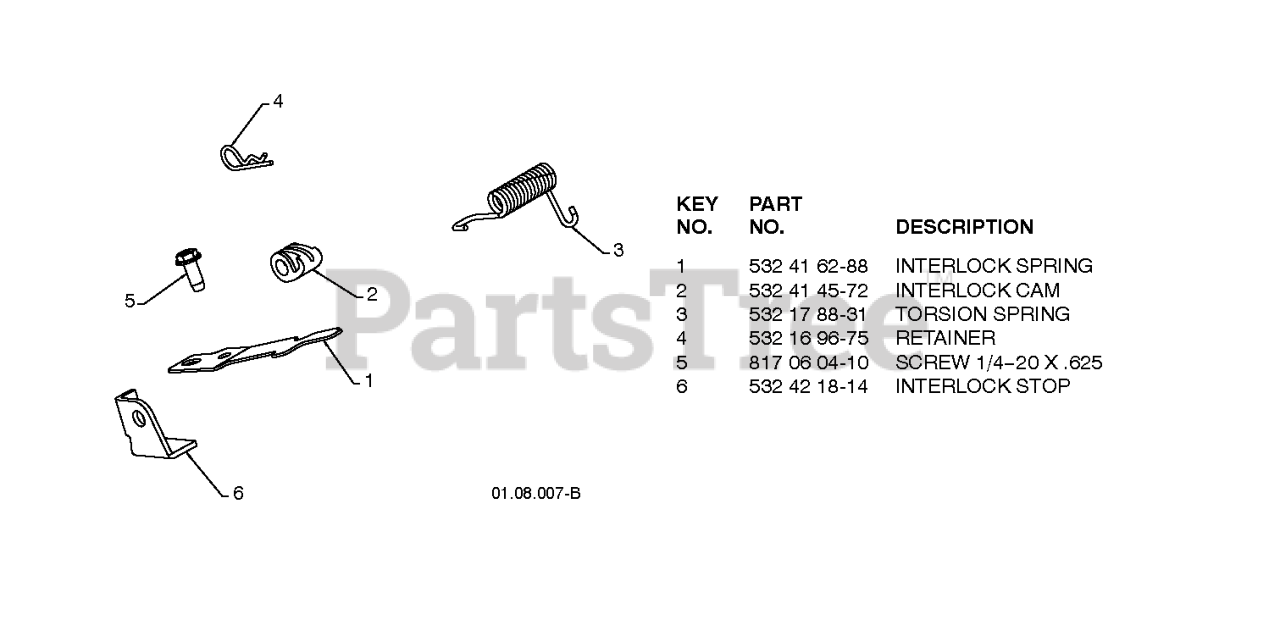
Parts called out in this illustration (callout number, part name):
1	SPRING.INTERLOCK
2	CAM.INTERLOCK.RELEASE
3	RP SPRING, TORSION
4	SPRING RETAINER
5	SCREW 14-20 X 5/8
6	STOP.INTERTLOCK
